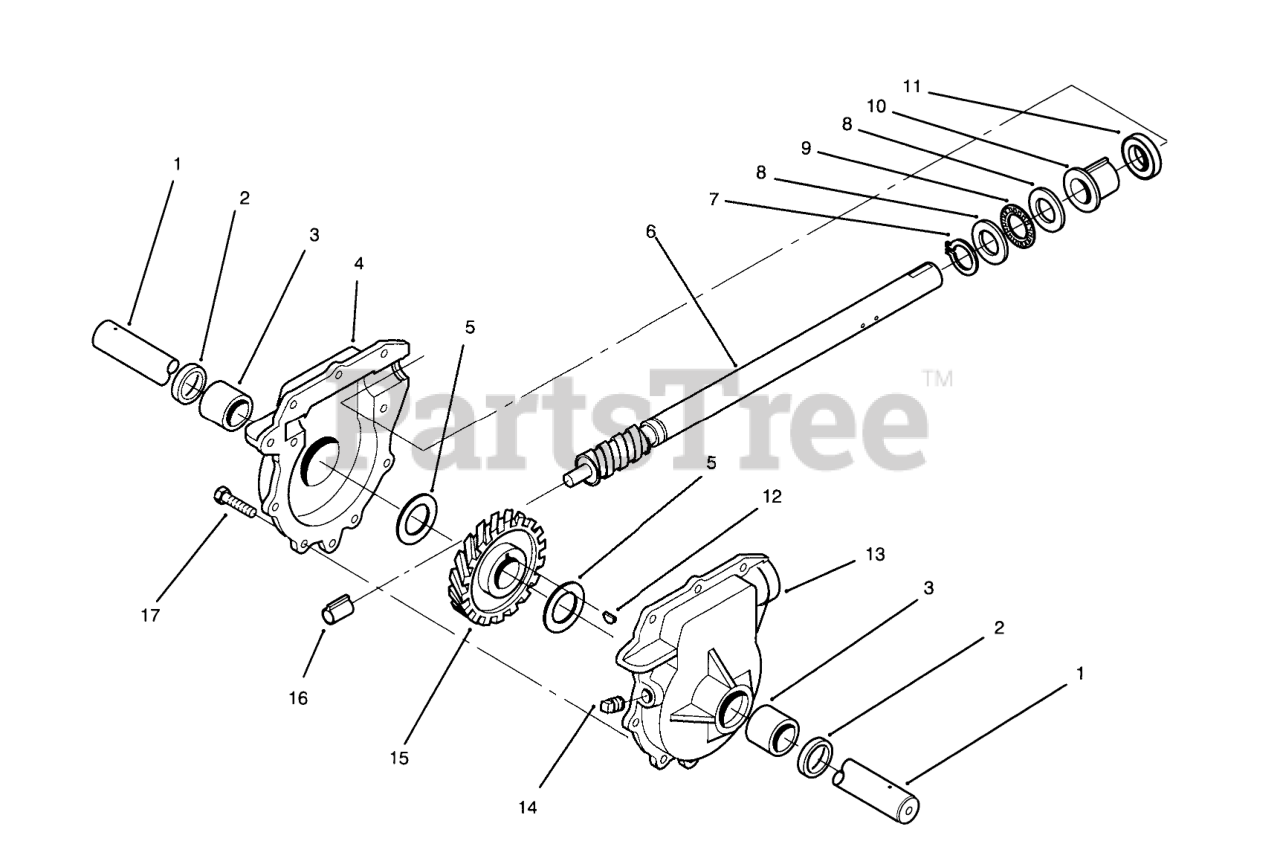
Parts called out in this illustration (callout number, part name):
1	SHAFT-AUGER
2	SEAL-OIL
3	BUSHING
4	Gearcase Assembly - R. H . (Incl. Ref. # 2-3)
5	WASHER-THRUST
6	SHAFT-IMPELLER
7	RING-RETAINING, Ext
8	WASHER-THRUST
9	BEARING-THRUST
10	BUSHING-INPUT
11	SEAL-OIL
12	KEY-WOODRUFF
13	Gearcase Assembly-L. H . (Incl. Ref. # 2-3, & 17)
14	PLUG-PIPE, SQH
15	GEAR-HELICAL
16	BUSHING-WORM
17	SCREW-HWH
